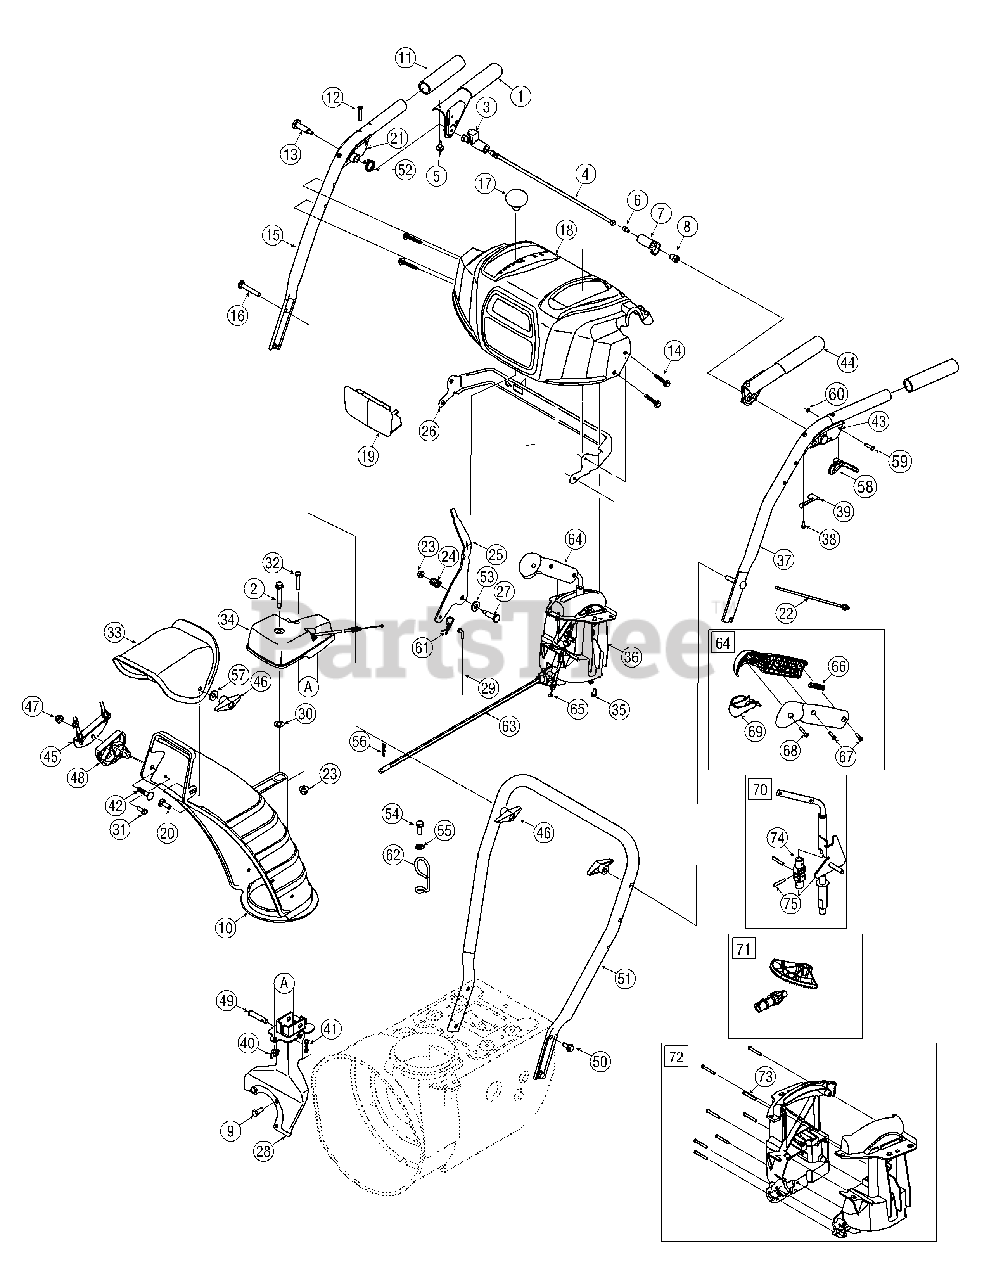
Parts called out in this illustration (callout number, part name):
1	Handle Engagement Assembly RH
2	Flange Shoulder Screw
3	Lock Plate
4	Pivot Rod
5	Rubber Bumper
6	Screw, 1/4-20 x .500
7	Clutch Lock Cam
8	Shoulder Nut, 1/4-20
9	Hex Screw, 5/16-24 x .750
10	Lower Chute
11	Handle Grip
12	Screw, #10-24 x 0.375
13	Shoulder Screw, 1/4-20
14	Screw, 1/4-20 x 1.625
15	Upper Handle RH
16	Carriage Screw, 5/16-18 x 2.25
17	Shift Knob
18	Handle Panel
20	Carriage Bolt, 5/16-18 x 1.0
21	Handle Clutch Lock RH Assembly
22	Cable Tie
23	Flange Lock Nut, 1/4-20
24	Compression Spring
25	Shift Lever
26	Panel Bracket
27	Shoulder Screw
28	Chute Support Bracket
29	Speed Selector Cable
30	Flat Washer, .25 x .630 x .0515
31	Hi-Lo Screw, 1/4-15 x .75
32	Hex Screw, 1/4-20 x 3.00
33	Upper Chute
34	4-Way Chute Gearbox Assembly
35	Hi-Lo Screw, 1/4-15 x 0.5
36	4-Way Chute Control™ Assembly
37	Upper Handle LH
38	Screw, #8-16 x 0.50
39	Clutch Lock Spring
40	Wing Nut, 1/4-20
41	Bow Tie Cotter Pin
42	Carriage Bolt, 5/16-18 x 1.50
43	Handle Clutch Lock LH Assembly
44	Handle Engagement Assembly LH
45	Cable Bracket
46	Wing Knob
47	Flange Lock Nut, 5/16-18
48	Chute Tilt Cable Guide
49	Clevis Pin
50	Screw, 5/16-18 x 0.75
51	Lower Handle
52	Torsion Spring
53	Flat Washer
54	Screw, M8-1.25
55	Flat Washer, .330 x .630 x .0635
56	Cotter Pin
57	Flat Washer, .349 x .879 x .063
58	Steering Control
59	Pin, 3/16
60	E-Ring
61	Click Pin
62	Cable Control Wire
63	Chute Rod
64	Handle Assembly
65	4-Way Cable
66	Handle Plunger
67	Screw, Mach., #8-32 x .750
68	Screw, #8 x 1.00
69	Handle Lever
70	Shift Assembly
71	Gear Set Assembly
72	Handle Housing Assembly
73	Screw, #8-18 x 1.250
74	Joint Block Assembly
